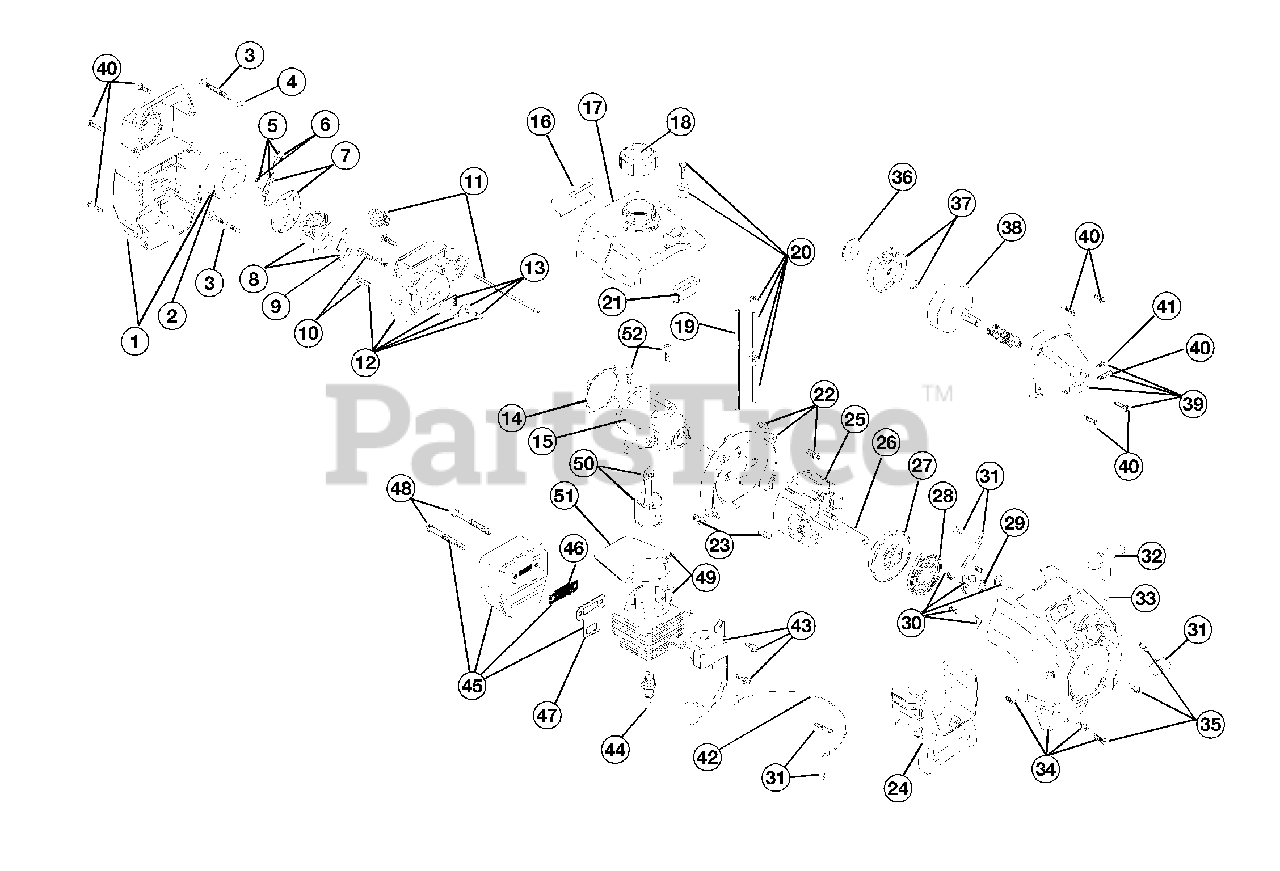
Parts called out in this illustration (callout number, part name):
1	Air Cleaner/Muffler Cover Assembly
2	Air Cleaner Filter
3	Carburetor Mounting Screw Assembly
4	Wavey Washer
5	Choke Lever Assembly
6	Choke Knob and Screw
7	Choke Lever and Plate
8	Carburetor Assembly
9	Carburetor Gasket
10	Carb Mount Screw
11	Primer and Hose Assembly
12	Carb Mount Assembly
13	Reed Assembly
14	Carburetor Mount Gasket
15	Crank Case Service Assembly
16	Rear Mounting Pad
17	Fuel Tank Assembly
18	Fuel Cap Assembly
19	Fuel Return Line
20	Fuel Line Assembly
21	Front Mounting Pad
22	Shroud Assembly
23	Shroud Screw
24	Shroud Extension and Stand
25	Flywheel Assembly
27	Recoil Pulley Assembly
28	Recoil Spring
29	Rope Guide
30	Pulley Retainer Assembly
31	Switch Assembly
32	Pull Handle
34	Starter Housing Assembly
35	Housing Screw
36	Clutch Washer
37	Clutch Rotor Assembly
38	Clutch Drum Assembly
39	Clutch Cover Assembly
41	Anti-Rotation Screw
42	Wire Lead
43	Module Assembly
44	Spark Plug
45	Muffler Assembly
46	Spark Arrestor Screen
47	Exhaust Gasket
48	Muffler Mounting Bolt
49	Cylinder Assembly
50	Piston and Rod Assembly
51	Cylinder Gasket
52	Cylinder Bolt
